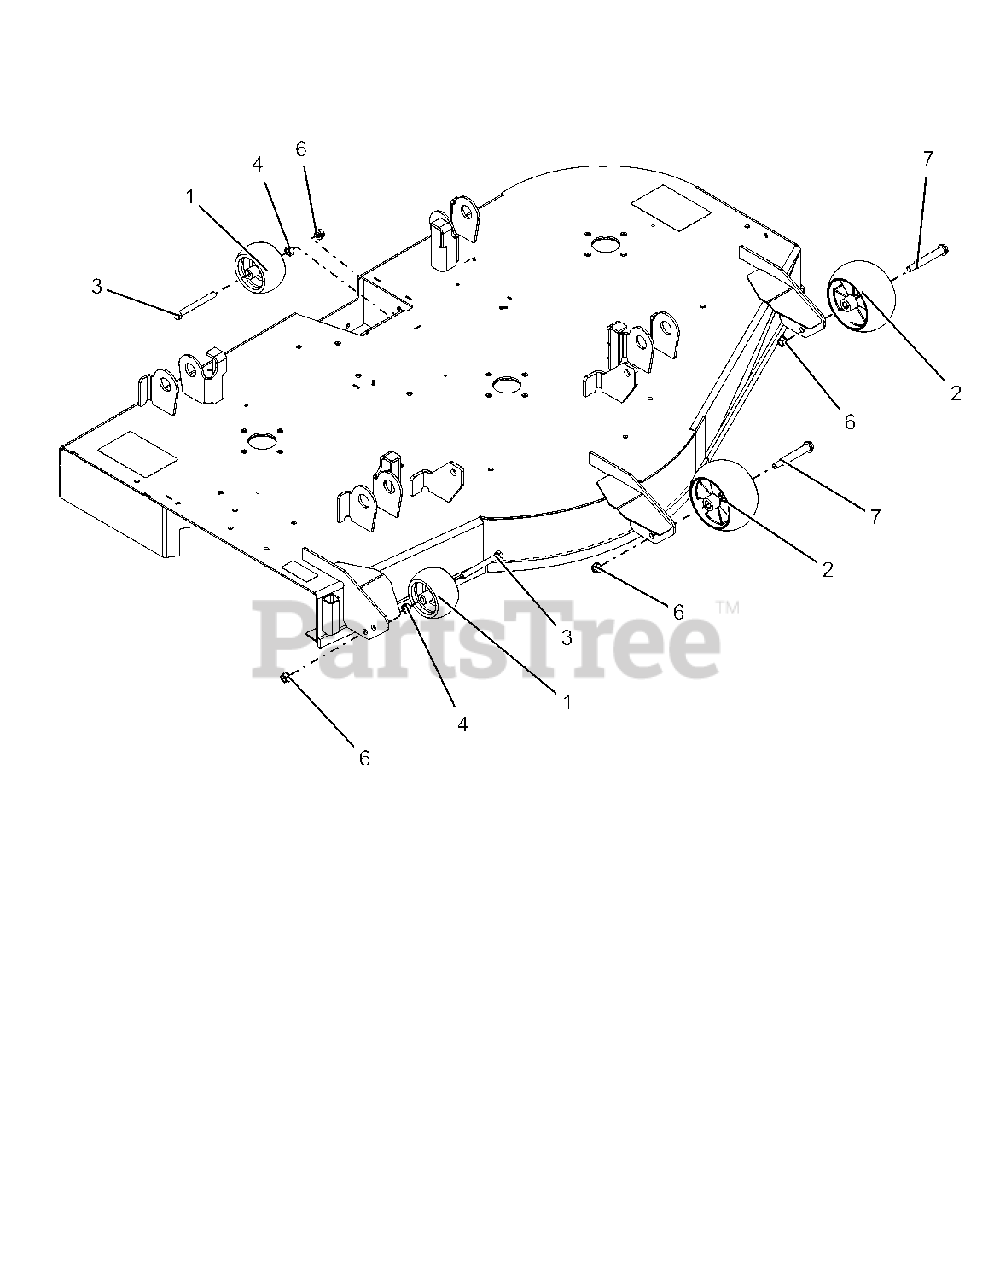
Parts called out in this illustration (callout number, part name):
2	ANTI-SCALP WHEEL - 5X OS
3	@BLT-HEX .38-16X3.50 GR5 YWZC
4	@NUT-HEX .38-16 YWZC
6	@NUT-LK-TOP-FLG .38-16 YWZC
7	BLT-SHLDR .38-16X2.50 HWH G5
